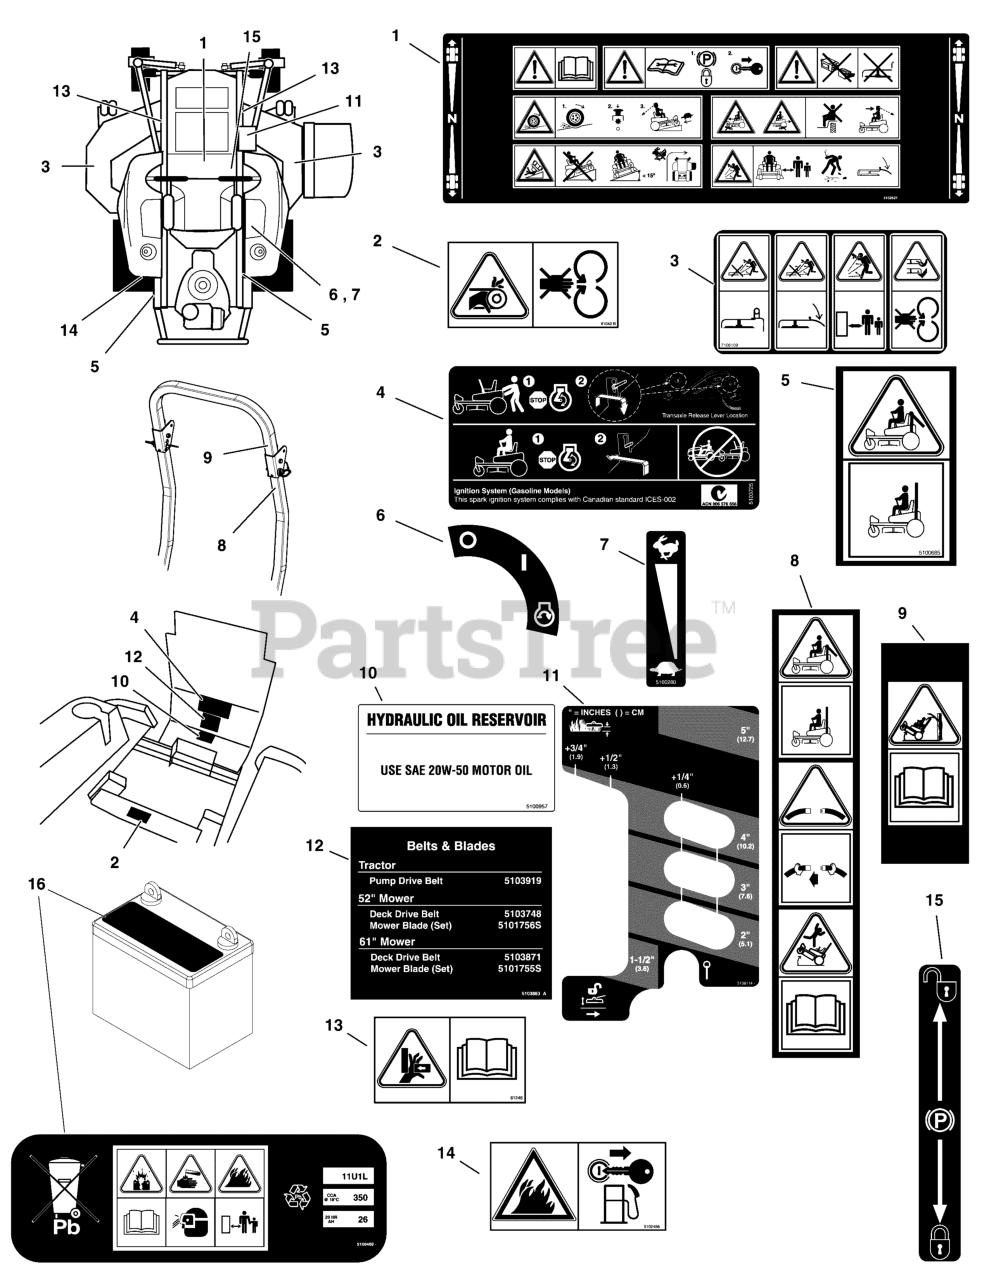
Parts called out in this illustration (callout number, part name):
1	DECAL, MAIN SAFETY, EXPORT
2	DECAL, CE DANGER, HAND IN BELT
3	DECAL, DISCHARGE SAFETY, EXPORT
4	DECAL, TRANSAXLE RELEASE, 600/700
5	DECAL, WARNING, ROLL BAE, CE
6	DECAL, IGNITION CONTROL
7	DECAL, Throttle Control
8	DECAL, SAFETY, CE ROPS (SV)
9	DECAL, SAFETY, CE ROPS, OBS (SV)
10	DECAL, HYDRAULIC OIL, SAE 20W50
11	DECAL, CUTTING HEIGHT
12	DECAL, BELT & BLADE, S125XT
13	DECAL, Pinch Point, CE
14	DECAL, FIRE ANSI EXPORT
15	DECAL, PARKING BRAKE SYMBOLS
16	DECAL, BATTERY, EXP, 11U1L
